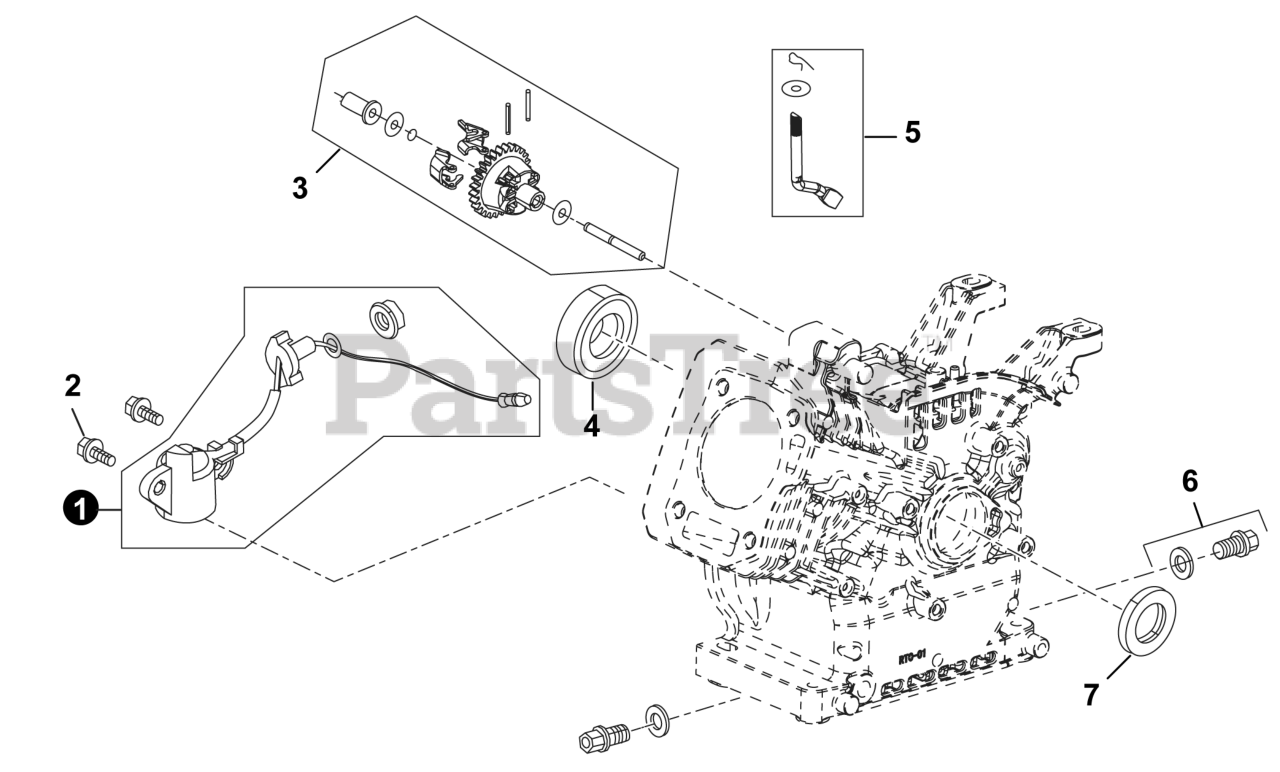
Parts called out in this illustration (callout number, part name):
1	SENSOR, ENGINE OIL
3	GEAR ASSY., GOVERNOR
4	BEARING, CRANKSHAFT
5	ARM, GOVERNOR
6	PLUG, OIL DRAIN
7	SEAL, OIL
